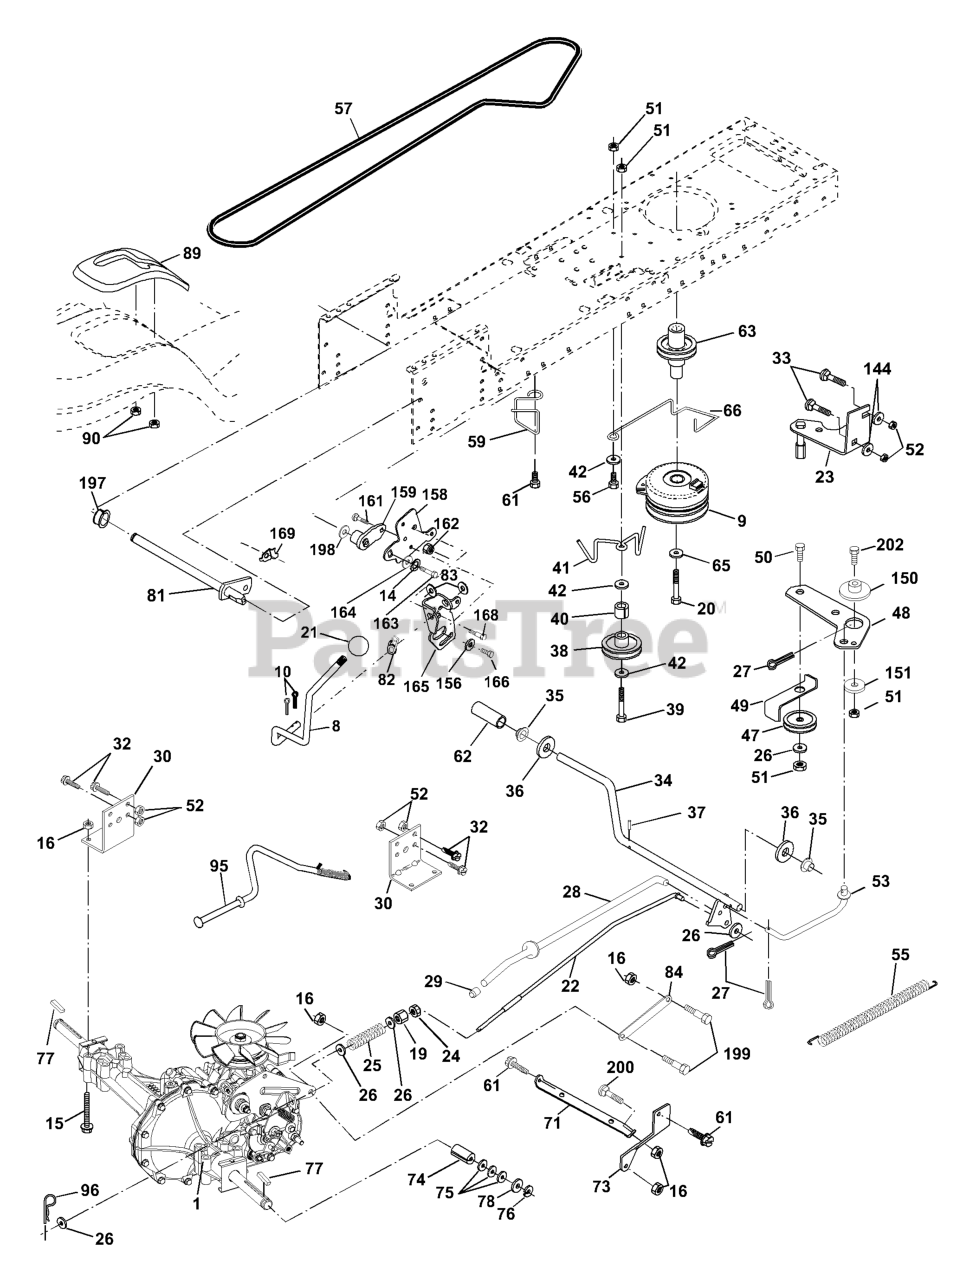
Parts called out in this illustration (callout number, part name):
1	Transaxle
8	ROD SHIFT FENDER ADJUST STLT
9	CLUTCH.ELECT.EVX.
10	PIN COTTER
14	LOCKWASHER
15	BOLT HEX 5/16-18 GR 5
16	NUT.71038.31-18.HEX.NYLOCK
19	NUT
20	BOLT HEX
21	KNOB.DUCKHEAD.1/2
22	ROD BRAKE HYDRO
24	NUT
25	SPRING ROD LT
26	WASHER
27	COTTER PIN
28	ROD BRAKE PARK LT
29	PLUNGER CAP
30	BRACKET TRANSAXLE
32	BOLT
33	RP BOLT 5/16-18 X3/4 ZN/YEL GR
34	SHAFT, FOOT PEDAL
35	BEARING.NYLON
36	WASHER LT
37	DRIVE PIN
38	FLAT IDLER PULLEY
41	KEEPER.BELT.IDLER.FLAT
42	WASHER
47	IDLER PULLEY
48	BELLCRANK, CLUTCH
49	RETAIN BELT
50	BOLT.3/8-16X1.50
52	LOCKNUT
53	LINK, CLUTCH LT
55	SPRING, RETURN LT
57	DRIVE BELT, LTH & YTH TRACTORS
59	KEEPER, BELT CENTER
61	SCREW 3/8-16X3/4
62	PEDAL COVER T
63	PULLEY, CLUTCH ELECT EVX
65	LOCKWASHER
66	KEEPER BELT ENGINE
71	STRAP TORQUE LH HYDRO
73	STRAP TORQUE RH HYDRO
74	SPACER AXLE
77	SQUARE KEY
81	SHAFT ASM CROSS TAPERED
82	SHIFT SPRING
83	WASHER
84	LINK TRANSAXLE
89	SHIFT CONSOLE
90	NUT.PUSH.3/16
95	CONTROL ASM. BYPASS HYDRO
96	RETAINER M
144	Washer 11/32 x 5/8 x 16 Ga.
150	BUSHING.BELLCRANK.GRD.DR
151	WASHER 12/32X2X10GA
156	WASHER.SRRTD.5/16
157	BOLT SHOULDER 5/16-18
158	BRACKET
159	HUB
161	BOLT
162	NUT.CROWNLOCK.1/4
163	BOLT
164	Washer 5/8 x 0281 x 10 Ga
165	RP BRACKET
168	BOLT.SHOULDER.5/16-18X
169	PLATE.FASTENING.CROSS.SHAFT
197	NYLINER SNAP 5/8" ID
198	WASHER.NYL.7/8IDX.105"HYD CR
199	BOLT SHOULDER 5/16-18 UNC
200	Bolt Rdhd Sq Neck 5/16-18 x 1 Unc
201	SCREW
